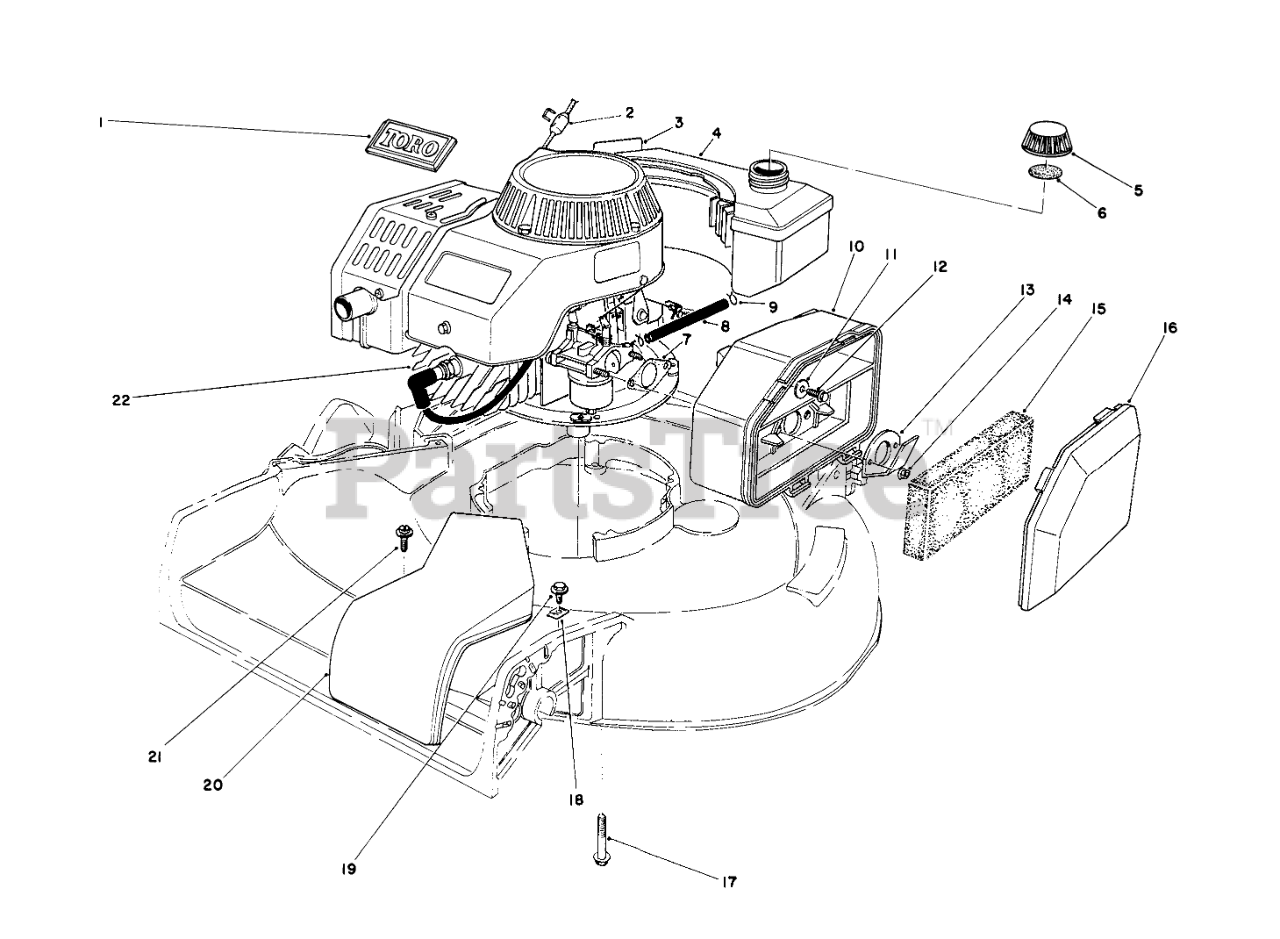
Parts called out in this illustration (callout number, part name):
1	TORO LOGO PLT
2	STOP-ROPE
3	Decal-Maintenance
4	Fuel Tank Assembly
5	Gas Cap Assembly (IncL Ref. #5)
6	GAS CAP GASKET
7	GASKET-AIR CLEANER
8	FUEL LINE
9	FUEL LINE CLAMP
10	AIR CLEANER
11	WASHER-FLAT
12	SCREW-HH
13	SPIT BACK DEFLECTOR
14	NUT-LOCK
15	FILTER
16	AIR CLEANER COVER
17	FLG SCREW,3/8-16X2.000
18	Cable Clamp
19	SCREW-HWHTF
20	Cow-Belt
21	SCREW
22	Engine
